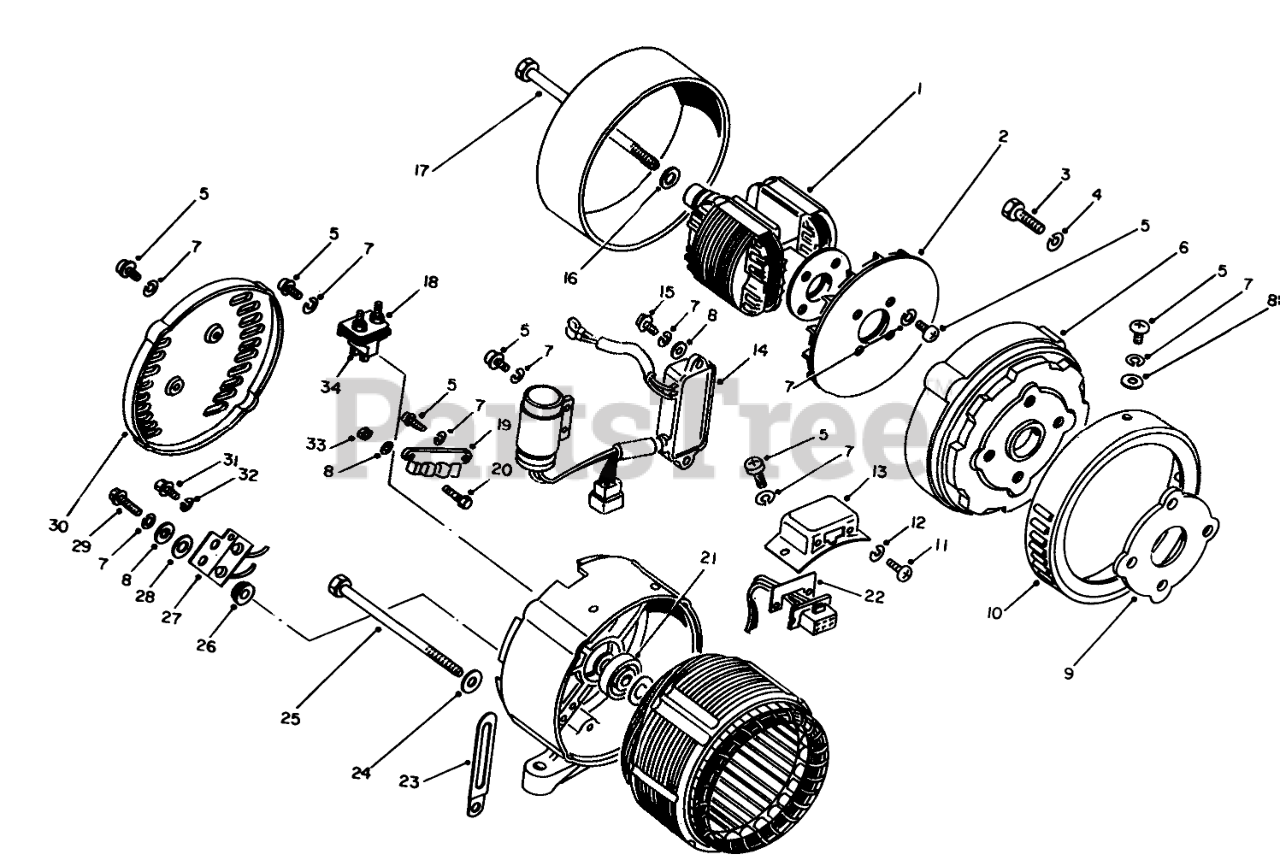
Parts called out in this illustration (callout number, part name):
1	Rotor
4	Lockwasher
5	SCREW
6	Generator Assembly (Incl.Ref. #1, 2, 5, 7, 16, 17, 821)
7	WASHER
8	WASHER
10	Cover-Front
11	SCREW
12	Lockwasher
13	COUPLER COVER
14	REGULATOR
15	Screw
16	Washer
18	Holder
19	Terminal
21	Bearing
22	Plate
23	Clamp
24	Washer
26	Brush
27	DIODE
28	Washer
29	Screw
32	Lockwasher
34	BRUSH
